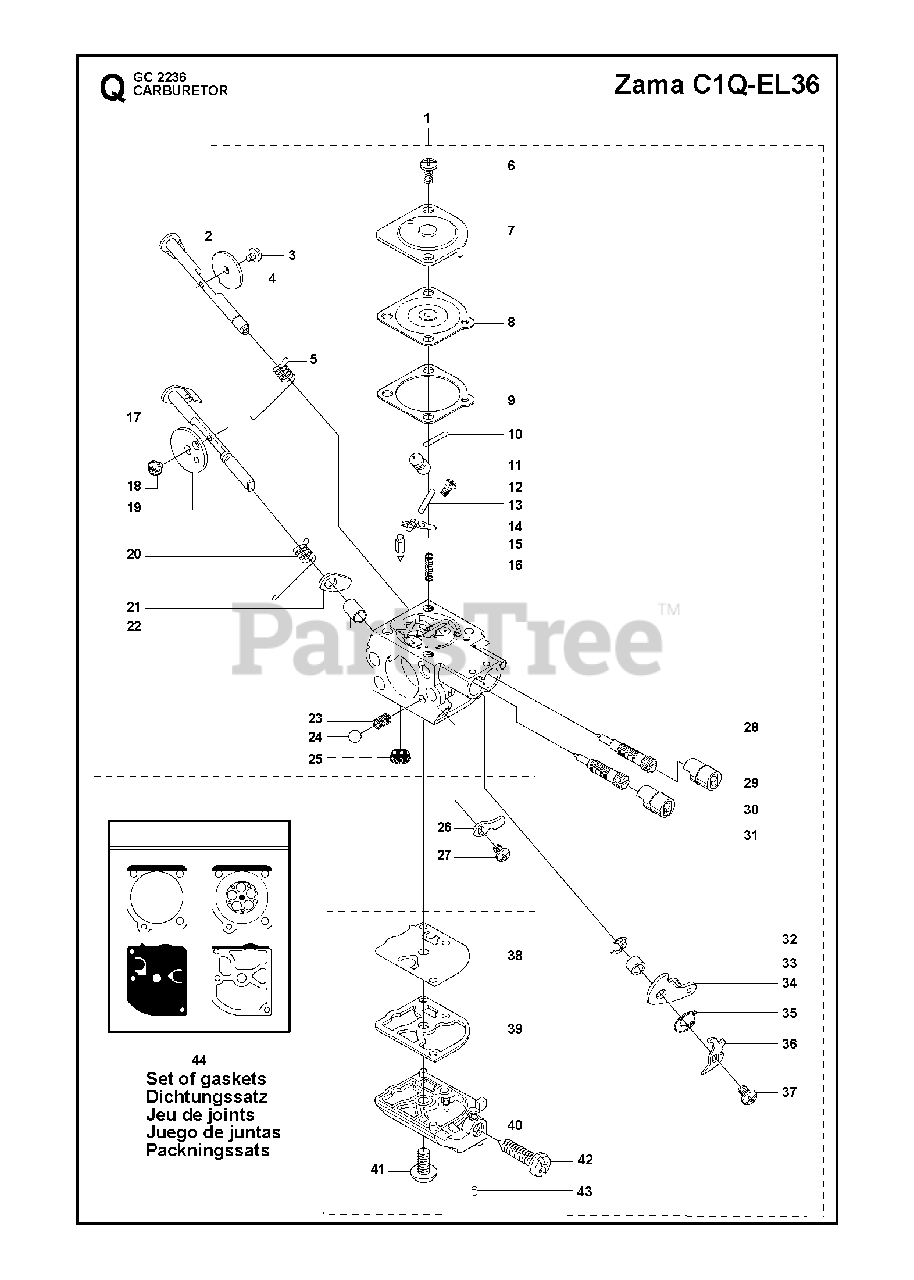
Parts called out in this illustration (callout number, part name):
1	CARBURETOR C1QEL36
2	THROTTLE SHAFT
3	SCREW
4	THROTTLE
5	RETURN SPRING
6	SCREW
7	COVER
8	DIAPHRAGM
9	GASKET
10	PLUG
11	JET
12	SCREW
13	PIN FULCRUM
14	LEVER
15	INLET NEEDLE
16	SPRING
17	CHOKE SHAFT
18	SCREW
19	DISC
20	SPRING
21	LEVER
22	SLEEVE
23	SPRING
24	BALL
25	FUEL INLET SCREEN
26	LEVER
27	SCREW
28	IDLE SCREW
29	LIMITER CAP KIT
30	LIMITER CAP KIT
31	SCREW
32	CLIP
33	SLEEVE
34	LEVER
35	SPRING
36	LEVER
37	SCREW
38	PUMP DIAPHRAGM
39	GASKET
40	COVER
41	SCREW
42	SCREW
43	PLUG
44	GASKET KIT (ZAMA GND39)
